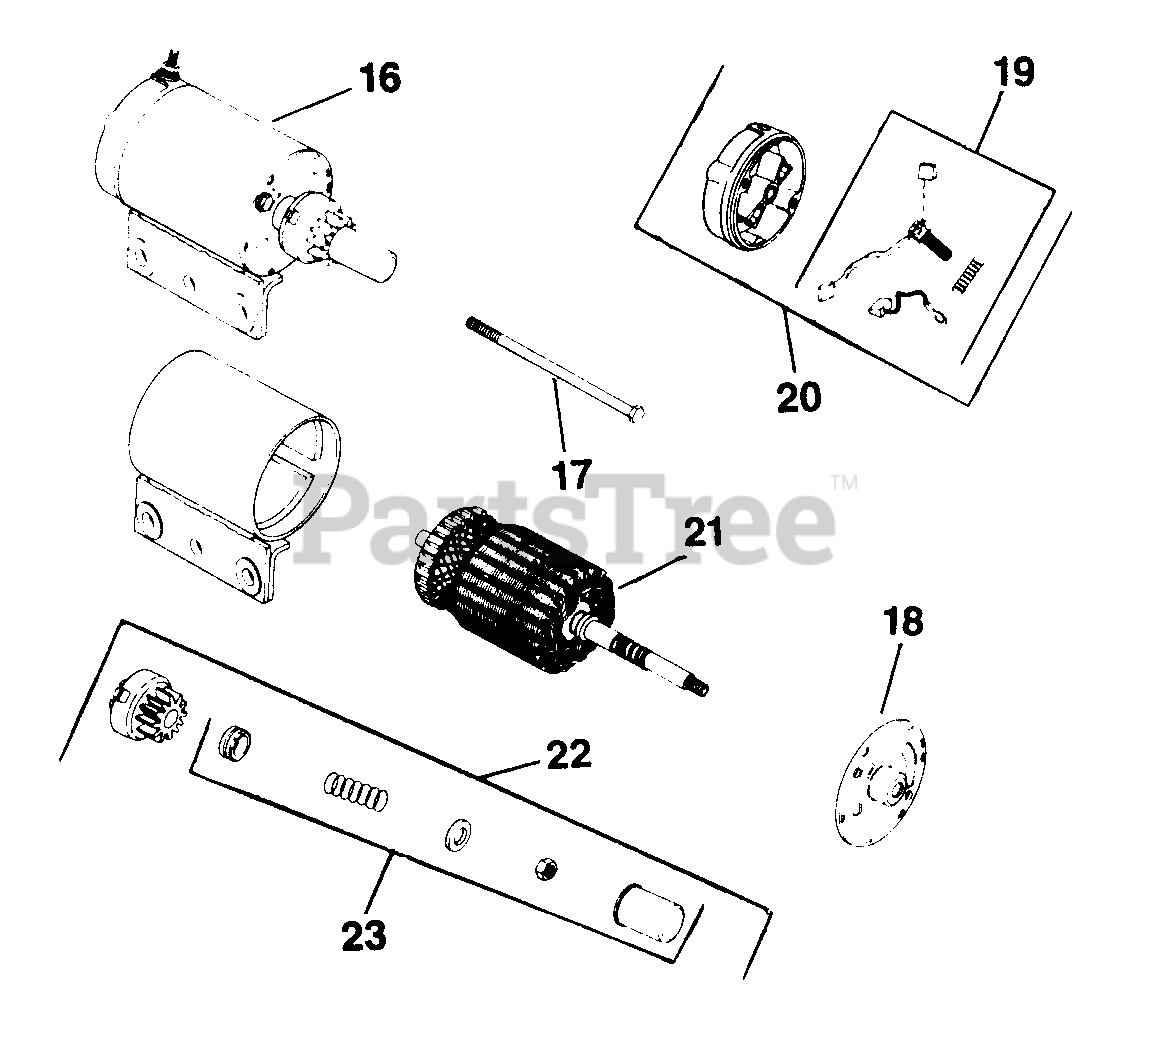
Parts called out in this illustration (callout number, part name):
16	STARTER - USE 45 098 03
18	CAP - USE 45 081 05
19	KIT - USE 82 755 28
20	CAP - DISCONTINUED
21	KIT, ARMATURE - DISCONTINUED
22	STARTER - USE 45 098 09
X-22-1-S	WASHER, SPRING LOCK 3/8"
